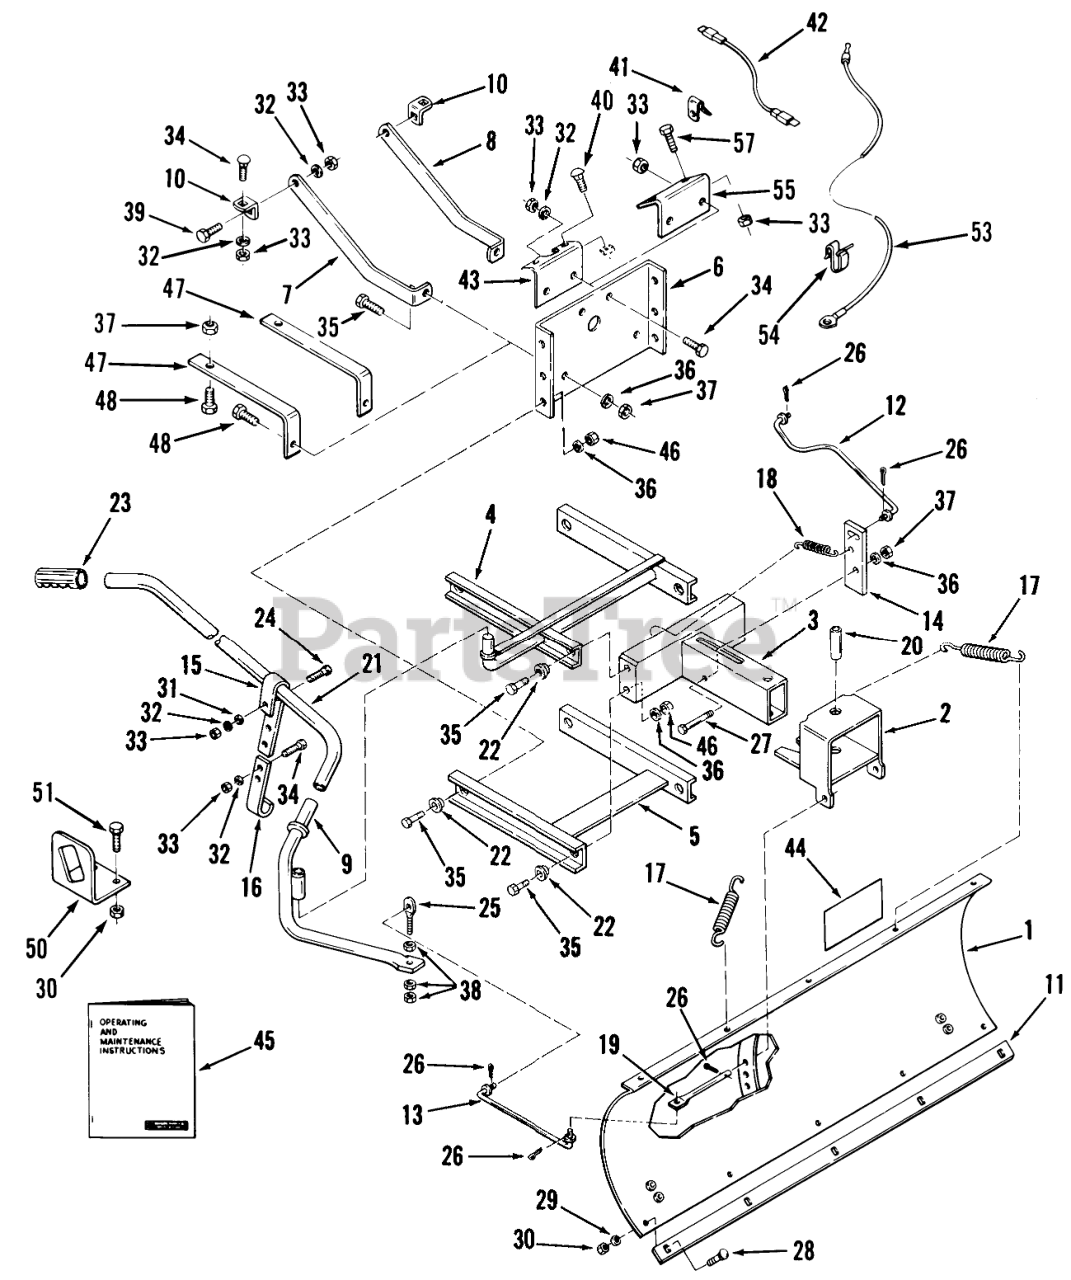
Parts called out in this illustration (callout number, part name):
1	Blade
2	Quadrant
3	Frame
4	Upper Parallel Bar
5	Lower Parallel Bar
6	Frame Mount
7	Frame Mount Brace RH
8	Frame Mount Brace LH
9	Lower Handle
10	CLIP FRAME
11	Blade Edge
12	LINK INDEX
13	Pivot Link
14	Index Bar
15	Upper Latch
16	Lower Latch
17	Trip Spring
18	SPRING-TENSION
19	PIN-QUADRANT
20	ROD-QUADRANT
21	Extension Handle
22	SPACER-PAR BAR
23	GRIP-HANDLE BAR
24	Bolt
25	Eye Bolt
27	Bolt
28	Bolt-Carriage
29	Washer
30	Nut
31	WASHER 5/16 SAE
32	Lockwasher
33	Nut
34	Bolt
35	Bolt 3/8-16 x 1
36	LOCKWASHER
37	Nut
38	Nut
39	Bolt-Carriage
40	Bolt
41	THROTTLE CONTROL CLP
42	Wire Assembly (For 1979 Models Only)
43	Mounting Plate
44	DECAL-WARNING
45	Operating and Maintenance Instructions (A-85, A-115, 100-Series)
45	Operating and Maintenance Instructions (A-51, A-81, A-111, RR-532, RR-832)
46	Nut Conlok 3/8-16
47	Lower Mounting Bracket
48	Bolt
50	Latch Bracket
51	Bolt
53	Wire 25" Long
54	SPEED CLIP
54	Clip 1/8" Wide
55	Upper Mounting Bracket
57	Bolt
